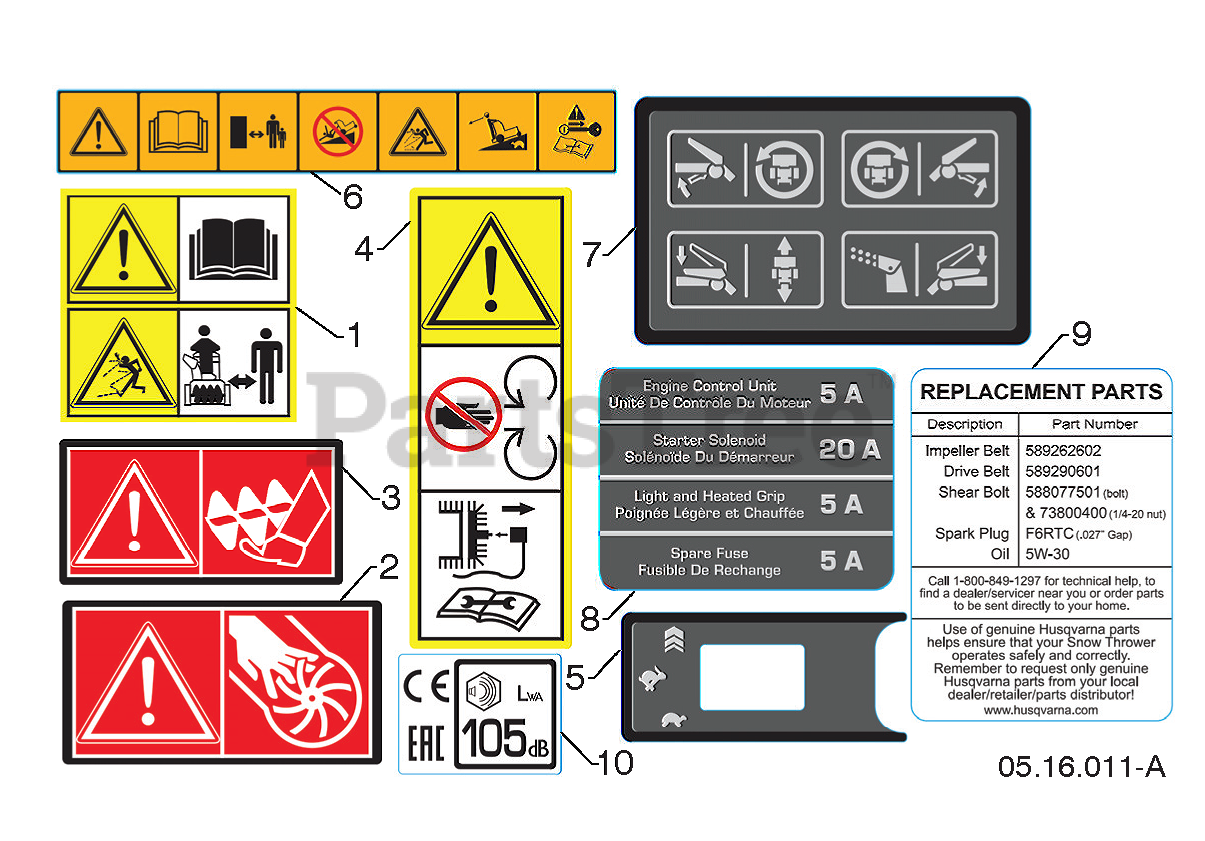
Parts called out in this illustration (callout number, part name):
1	DECAL.AUGER."
2	DECAL.CHUTE.SAFETY.EU/SC.17
3	DECAL.AUGER.SAFETY.
4	DECAL.BELT.GUARD.
5	DECAL SNOW CONSOLE GRAPHIC DEC
6	DECAL SNOW CONSOLE GRAPHIC DEC
7	DECAL SNOW CONSOLE GRAPHIC DEC
8	DECAL SNOW BATTERY BOX GRAPHIC
9	DECAL SNOW BATTERY BOX GRAPHIC
10	DECAL.NOISE.LEVEL.105DB/CE.EAC
